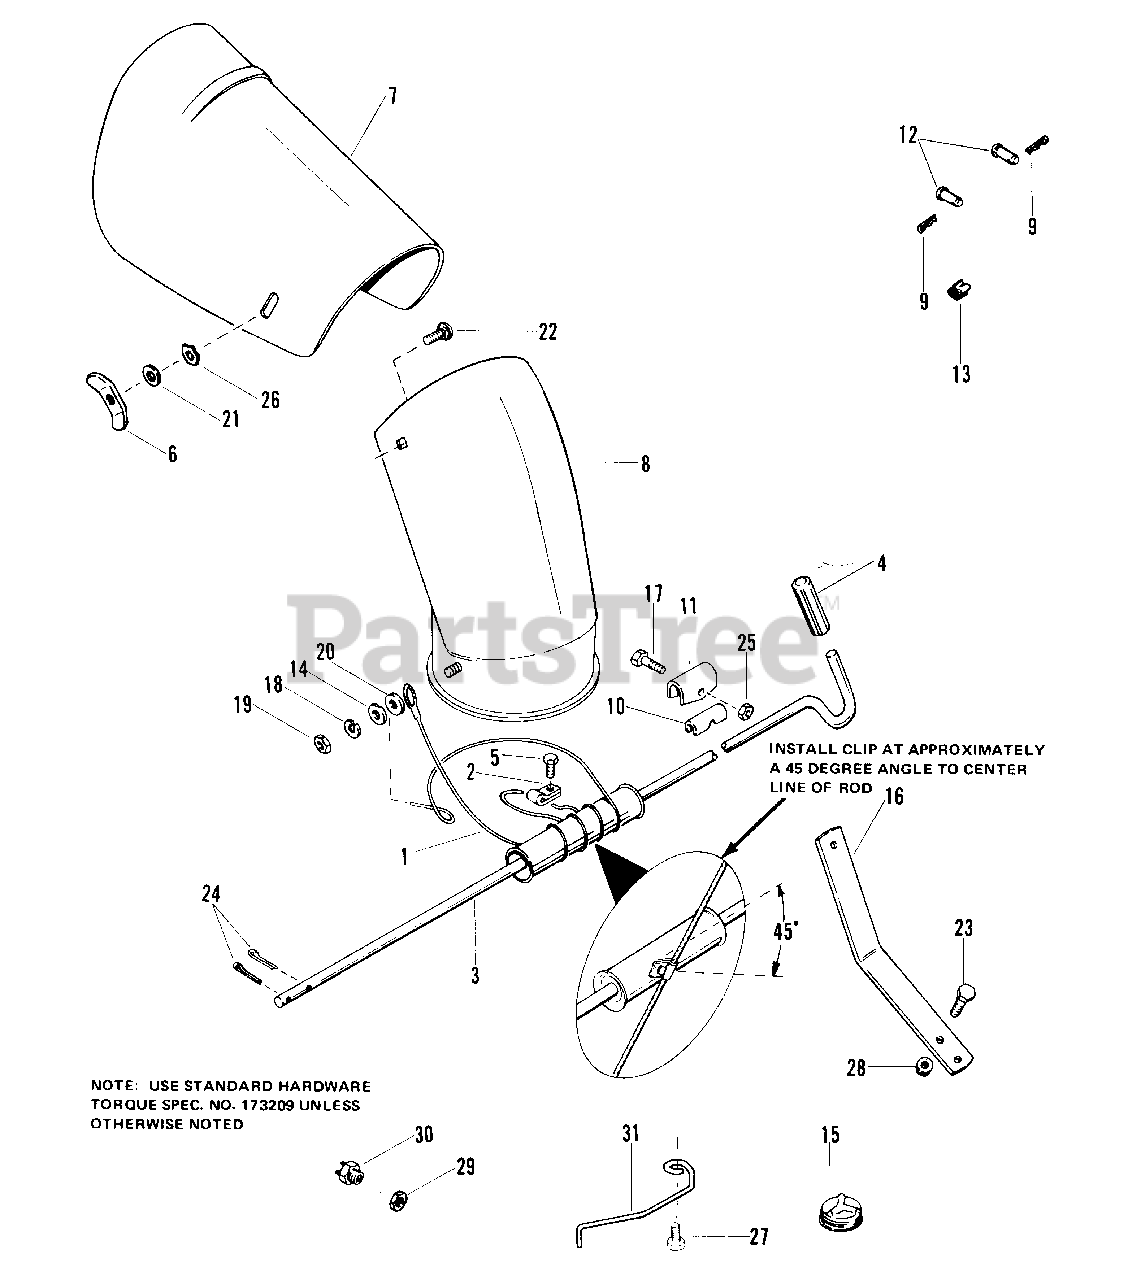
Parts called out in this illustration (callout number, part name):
1	CABLE ASSEMBLY
3	ROD ASSEMBLY, Spout Control
4	HANDLE GRIP
5	SCREW, Washer Hd., Taptite, 1/4-20 x 3/8
6	NUT, Wing, 5/16-18
7	EXTENSION, Spout
8	SPOUT ASSEMBLY
9	CLIP, Spring
10	GUIDE, Liner
13	CLIP, Speed
14	WASHER, Cup
15	CAP, Fuel Tank, Winterized
16	SUPPORT, Bracket
17	CAPSCREW, Hex Hd., 5/16-18 x 1 1/4
18	LOCKWASHER, 5/16
19	NUT, Hex, 5/16-18
20	WASHER, Plain, 1/4
21	WASHER, Plain, 3/8
22	BOLT, Carriage, 5/16-18 x 3/4
23	CAPSCREW, Hex Hd., 3/8-16x 1
24	PIN, Cotter
25	LOCKNUT, 5/16
26	LOCKWASHER, Pyramidal, 3/8
27	SCREW, Hex Washer Hd., Taptite, 5/16-18 x 5/8
28	NUT, Flange, 3/8
29	LOCKNUT, 9/16-18
30	INTERLOCK SWITCH
31	STOP, Belt
